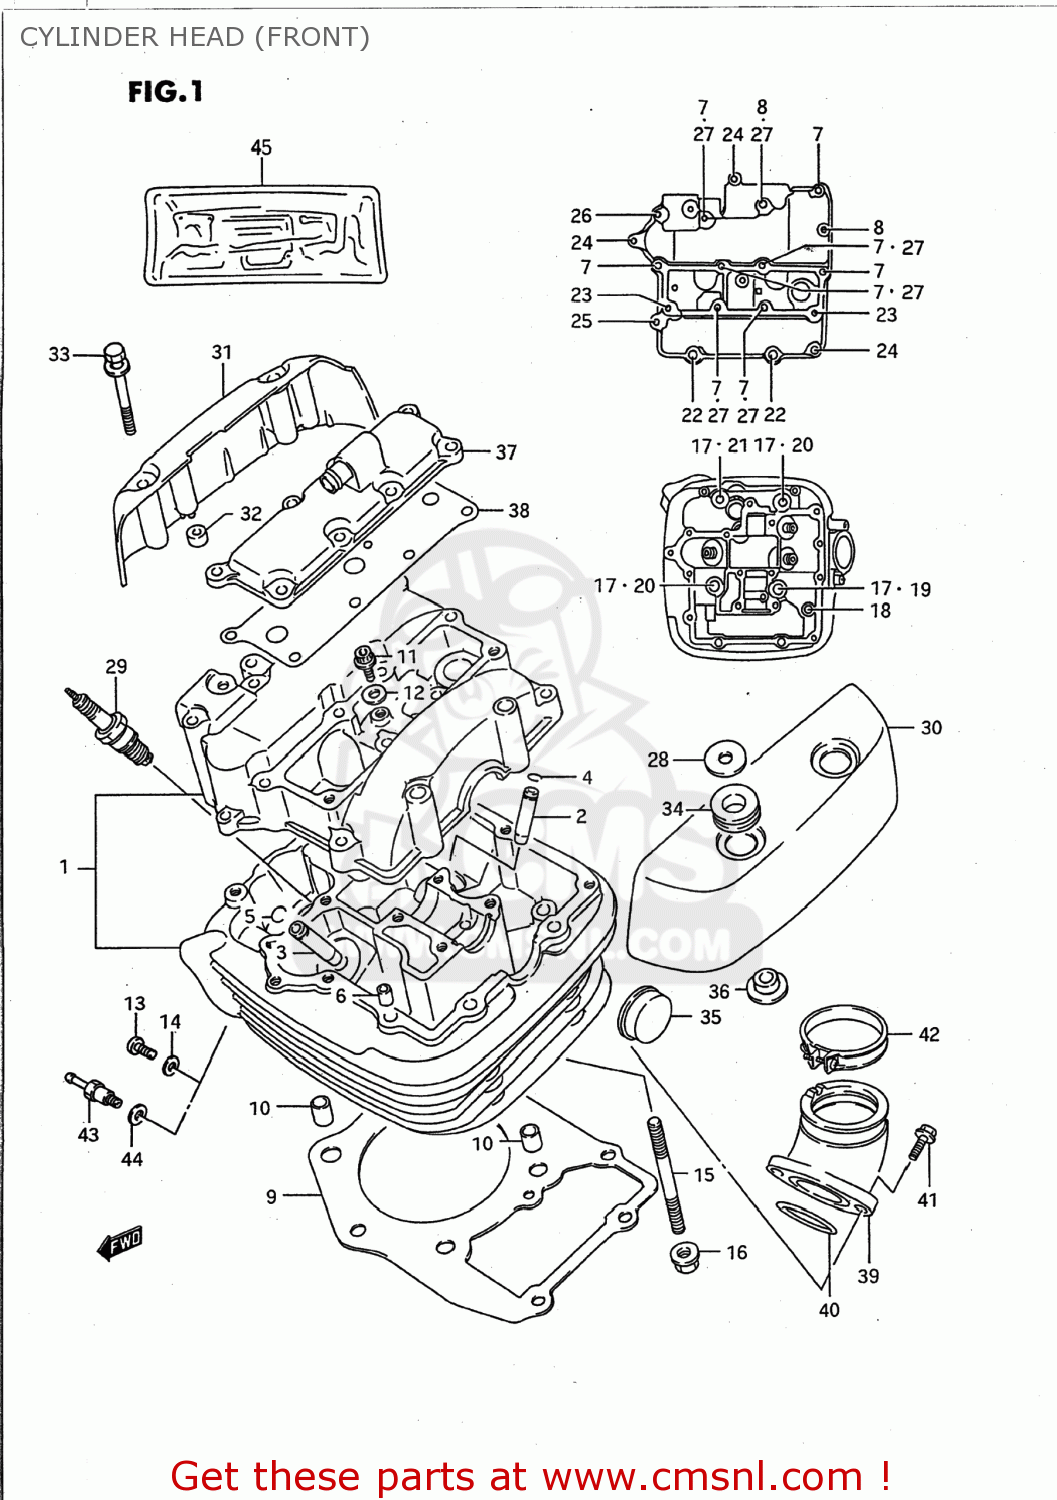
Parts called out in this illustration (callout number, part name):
1	HEAD ASSEMBLY,CYLINDER,FRONT
2	GUIDE,INTAKE VALVE
3	GUIDE,INTAKE VALVE
4	RING,SNAP
5	RING,SNAP
6	PIN(6.2X8X11)
7	BOLT
8	BOLT(6X55)
9	GASKET,CYLINDER HEAD FR (NAS)
10	PIN
11	BOLT
12	GASKET(6.2X13X1.2) (NAS)
13	SCREW
14	GASKET(5.3X9.3X1.2) (NAS)
15	BOLT,STUD
16	NUT
17	WASHER(10.5X22X2.3)
18	BOLT(8X70)
19	BOLT(10X180)
20	BOLT(10X190)
21	BOLT(10X200)
22	BOLT(8X268)
23	BOLT
24	BOLT
25	BOLT
26	BOLT
27	GASKET(5.8X13X1.2) (NAS)
28	WASHER (8.2X24X1.6)
29	SPARK PLUG DP8EA-9
30	CAP,CYLINDER HEAD COVER FL
31	CAP,CYLINDER HEAD COVER FR
32	CUSHION,R CAP
33	BOLT
34	CUSHION
35	PLUG(OD:30)
36	BUSH
37	COVER,BREATHER
38	GASKET (NAS)
39	PIPE ASSEMBLY,INTAKE,FRONT
40	O RING(D:2.4,ID:41.7)
41	BOLT
42	CLAMP
43	BOLT UNION
44	GASKET(6.2X13X1.2) (NAS)
45	GASKET SET (NAS)
